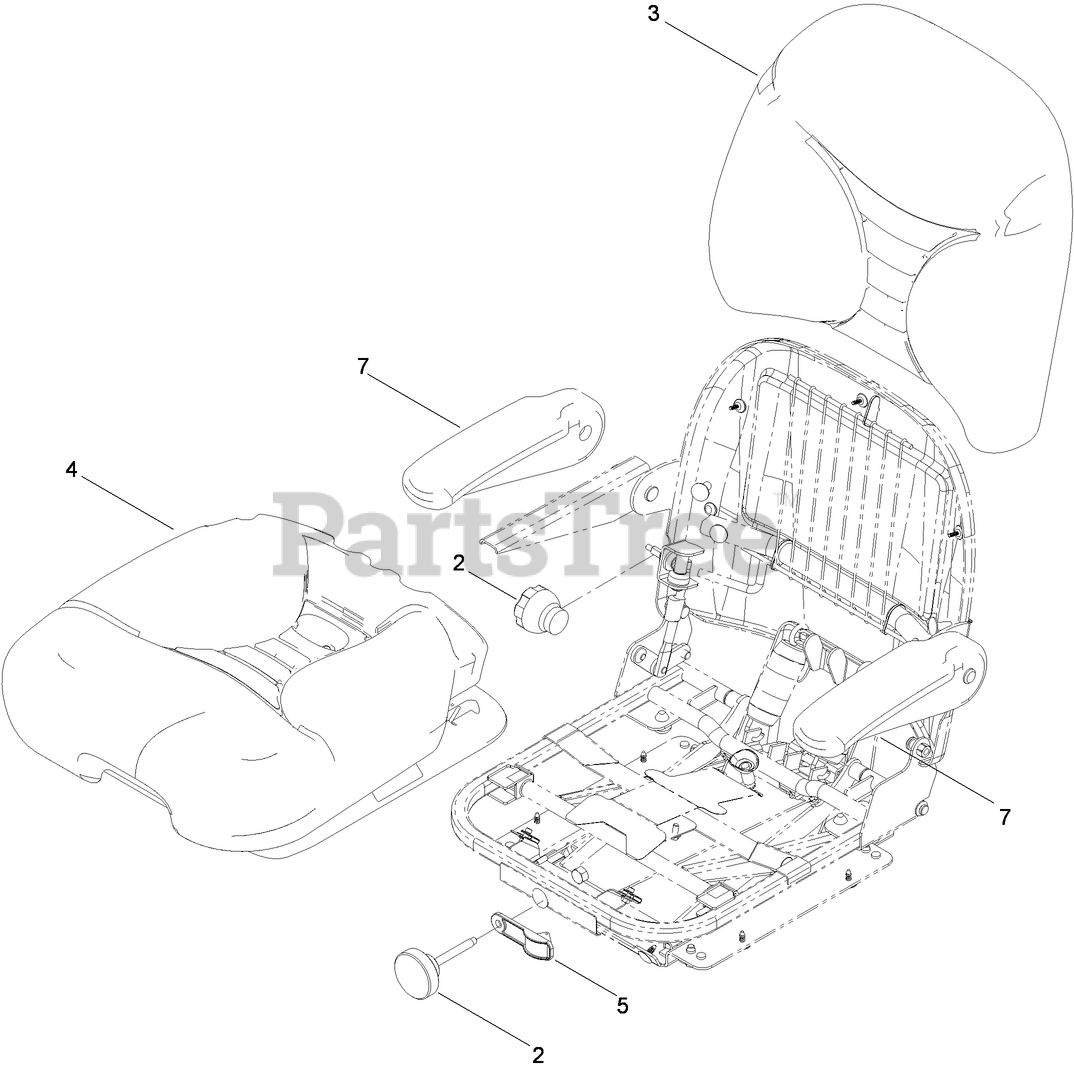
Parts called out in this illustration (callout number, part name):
2	Knob Kit
3	Back Cushion Kit
4	Bottom Cushion Kit
5	Weight Indicator Kit
7	PAD-ARMREST
